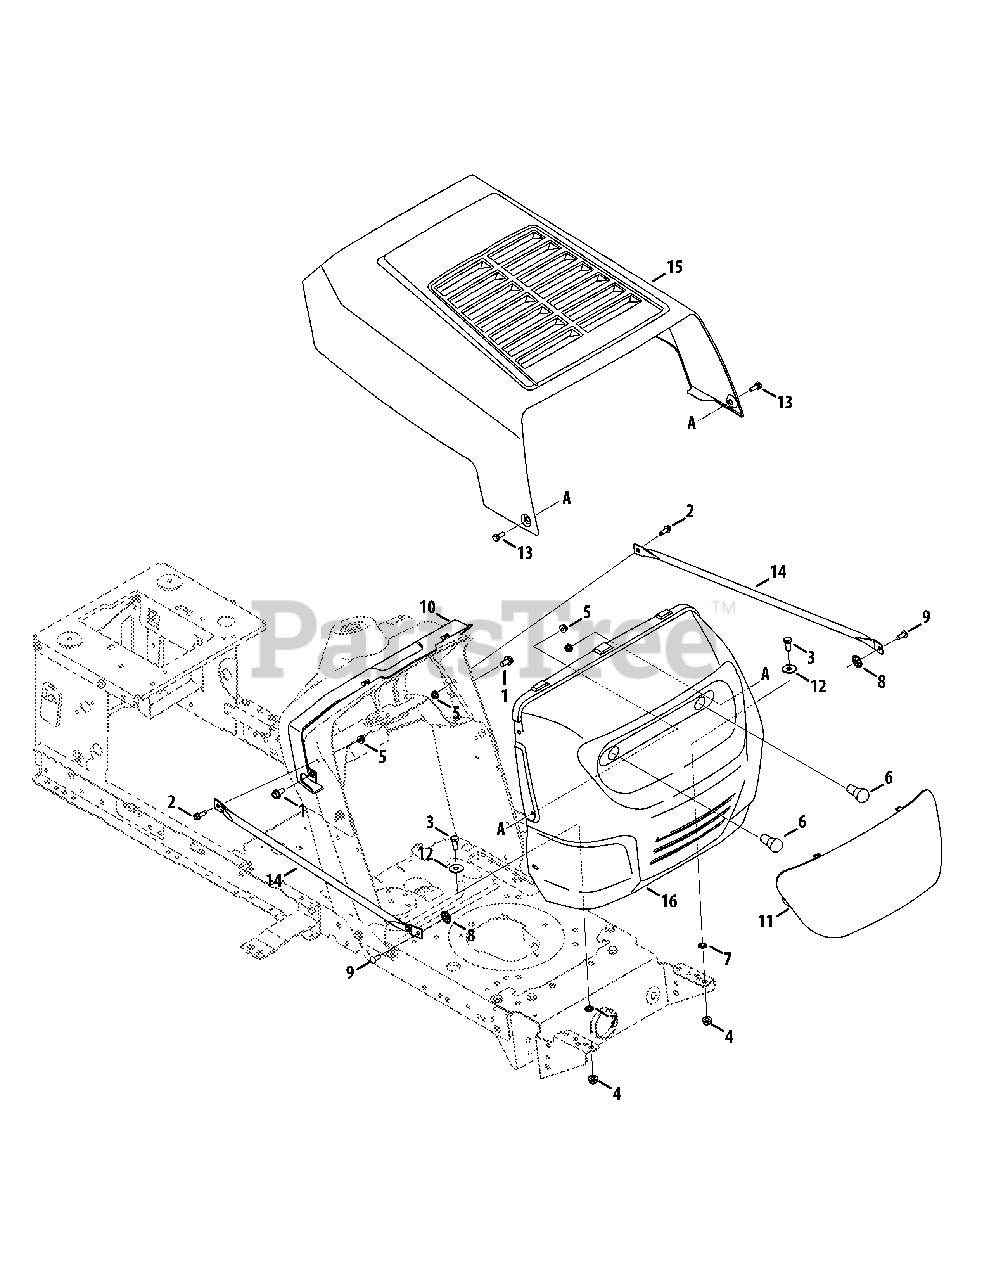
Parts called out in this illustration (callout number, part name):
1	Screw, 5/16-18 x .750
2	Screw, 1/4-20 x .750
3	Hex Screw, 5/16-18 x .75
4	Flangelock Nut, 5/16-18
5	Flangelock Nut, 1/4-20
6	Miniature Lamp 12V Socket
7	Speed Nut
8	Push-On Nut
9	Flat Head Rivet, 1/4"
10	Dash Collar
12	Flat Washer, .344 x 1.0 x .063
13	Shoulder Bolt, 1/4-20 x .375 x .125
14	Grill Support Rod
15	Hood - Red
15	Hood - Green
16	Grill - Red
16	Grill - Green
